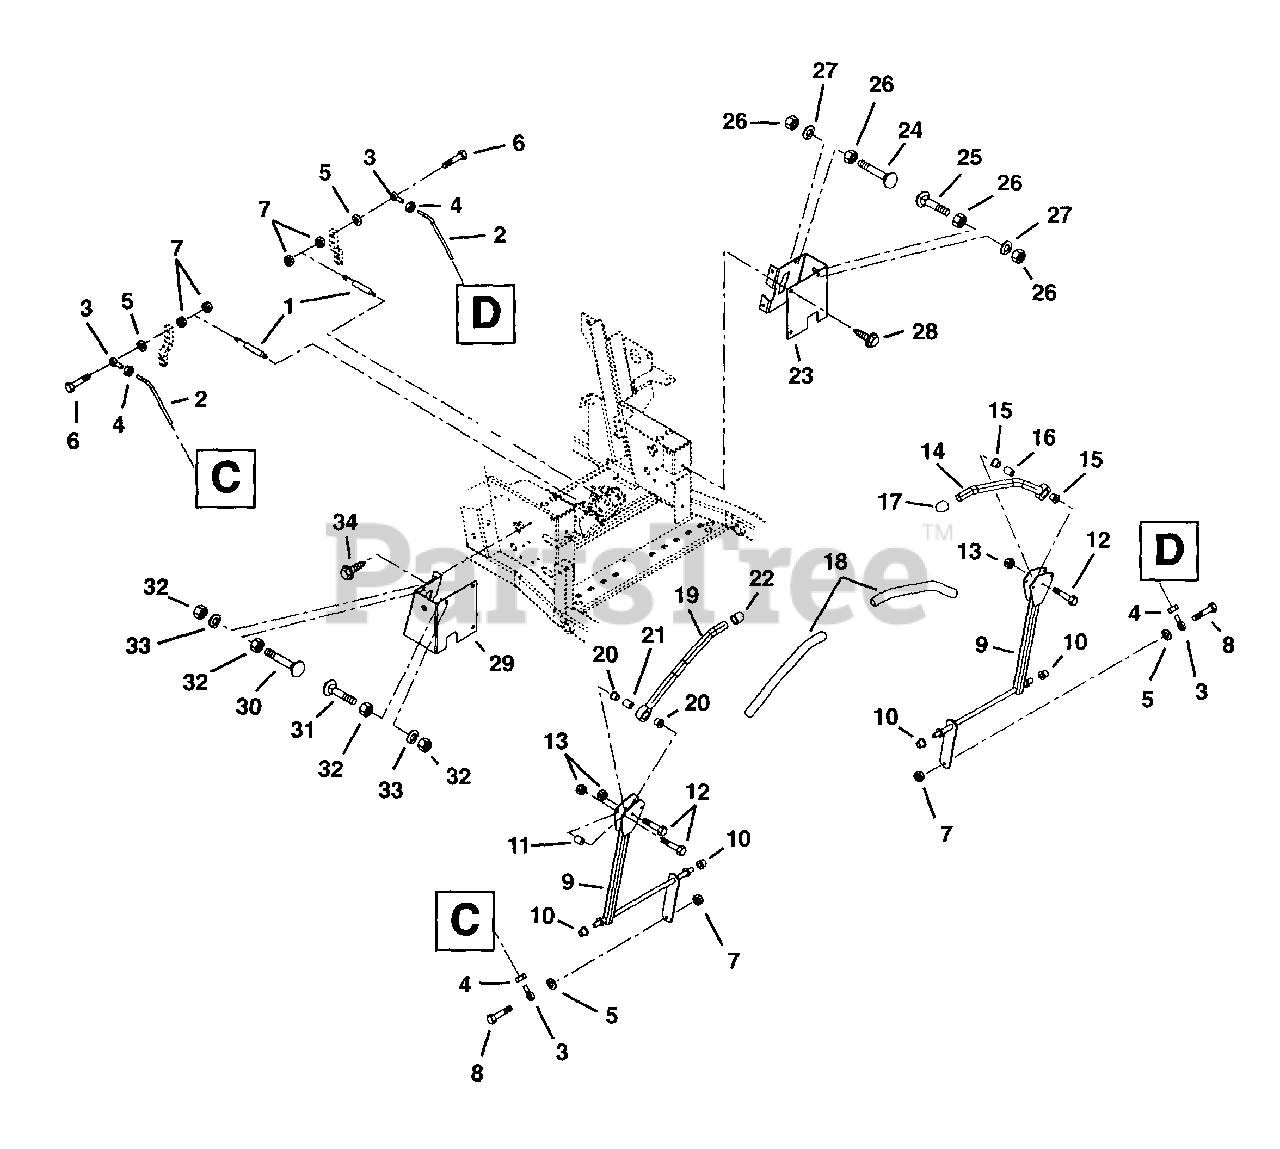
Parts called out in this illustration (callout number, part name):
1	Spring-Tension .062 x .56 x 8.0
2	Rod-Steering Adjustment
3	Rod End 5/16 Right-Hand-Female
4	Nut-Jam .31-24
5	Washer-Locking .31 x .078
6	Bolt-Hex .31-18 x 1.75 Grade 5
7	Nut-Locking-Center .31-18
8	Bolt-Hex .31-18 x 1.50 Grade 5
9	Rod-Steering
10	Bushing-Flange .515 x .750 x .745 x 1.00
11	Eccentric
12	Bolt-Hex .31-18 x 1.75 Grade 5
13	Nut-Locking-Center .31-18
14	Handle Weldment Left-Hand
15	Bushing-Flange-Nylon .762 x 1.48 x .44
17	End Cap-Steering Lever Tube
18	Grip-Handlebar
19	Handle Weldment Right-Hand
20	Bushing-Flange-Nylon .762 x 1.48 x .44
22	End Cap-Steering Lever Tube
23	Mount-Steering Rod-Left Hand
24	Bolt-Round Head Square Neck .38-16 x 2.00
25	Bolt-Round Head Square Neck .38-16 x 1.50
26	Nut-Hex .38-16
27	Washer-Locking .38 x .094
28	Screw-Tapping .38-16 x .75 Hex Washer Head
29	Mount-Steering Rod-Right Hand
30	Bolt-Round Head Square Neck .38-16 x 2.00
31	Bolt-Round Head Square Neck .38-16 x 1.50
32	Nut-Hex .38-16
33	Washer-Locking .38 x .094
34	Screw-Tapping .38-16 x .75 Hex Washer Head
